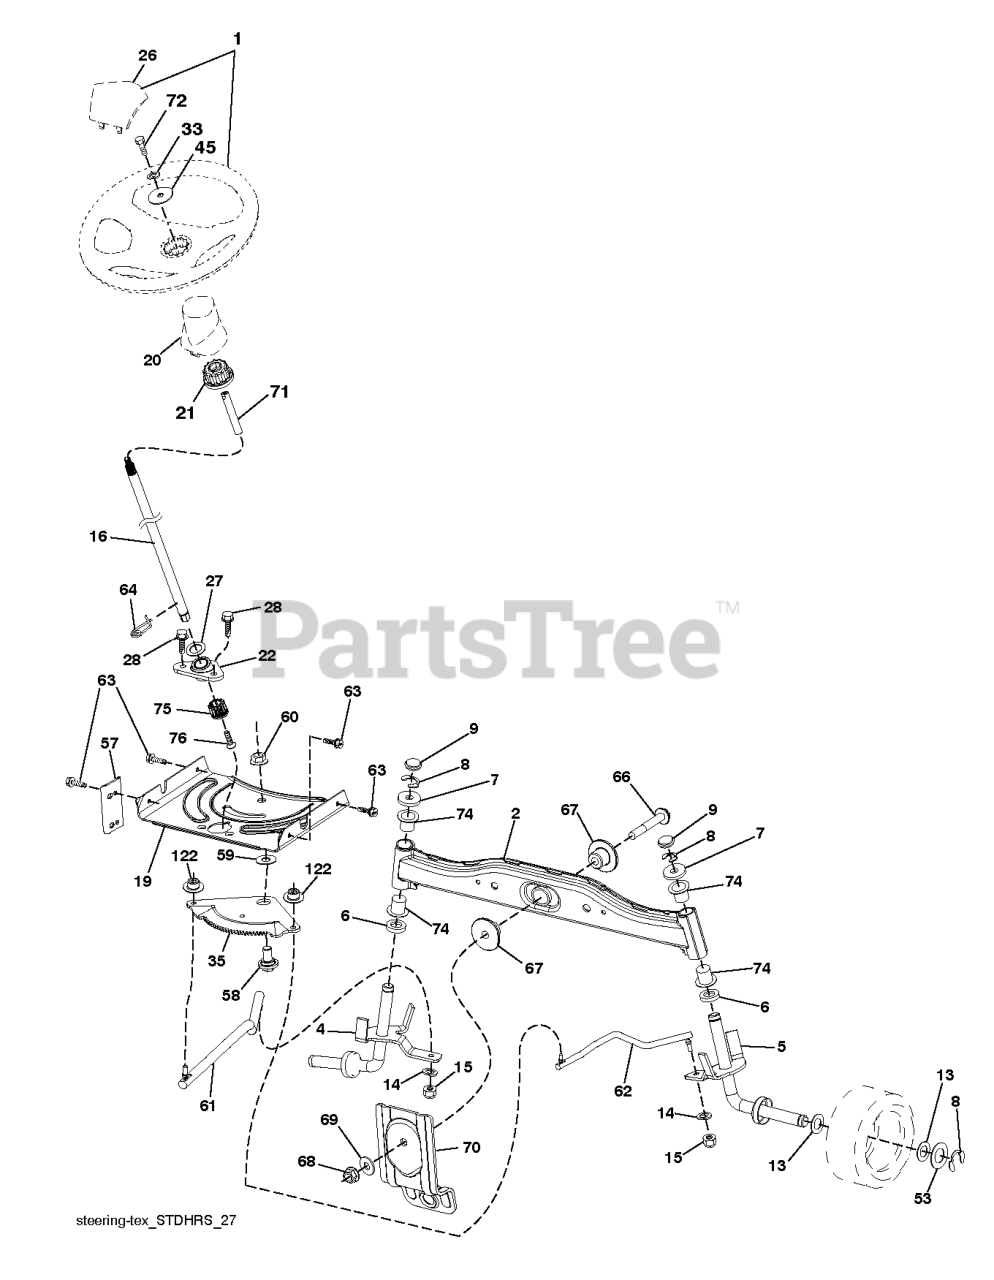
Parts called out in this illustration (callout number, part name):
1	Service Kit
2	AXLE HALF ASM-WELDED
4	SPINDLE.STEERING.ASM.LH.13".TI
5	SPINDLE.STEERING.ASM.RH.13".TI
6	WASHER THRUST
9	CAP.SPINDLE.BLACK
15	NUT CROWNLOCK 3/8-24
16	3 HIGH.SHAFT-ZINC.PLATED
19	PLATE.STEER.DDL.NLT/NG
20	STEERING.BOOT.HUSQ.LT
21	ADAPTER, WHEEL STNG..
22	BEARING.SHAFT.STEER.LOWER.625
28	SCREW, 3/8-16X3/4
33	WASHER SPRING LOCK WASHER WITH
35	GEAR.SECTOR.PLATE.DDL.
53	WASHER.HARDENED
57	BRACKET.UPSTOP.TEX
58	BOLT.SHOULDER.SECTOR.P
59	WASHER.THURST.SECTOR.S
60	NUT FLANGE LOCK 5/8-11
63	SCREW
64	RETAINER.CLIP.SPRING.S
66	BOLT HEX FGHD 7/16-14 X 3 SERR
67	BUSHING.PM.FRONT AXLE
68	NUT.LOCK.FLANGE.7/16
69	WASHER.1.5X.505X.118
70	BRACKET.SUSP.MWR.FRT.30"SRD
71	SHAFT.EXTEN.STRG.SPLINE
74	BEARING.STEERING.COLUMN
75	PINION.ZINC PLATED
76	SCREW HEAD SOCKET LRVB
122	CAP.GEAR.SECTOR.TEX
